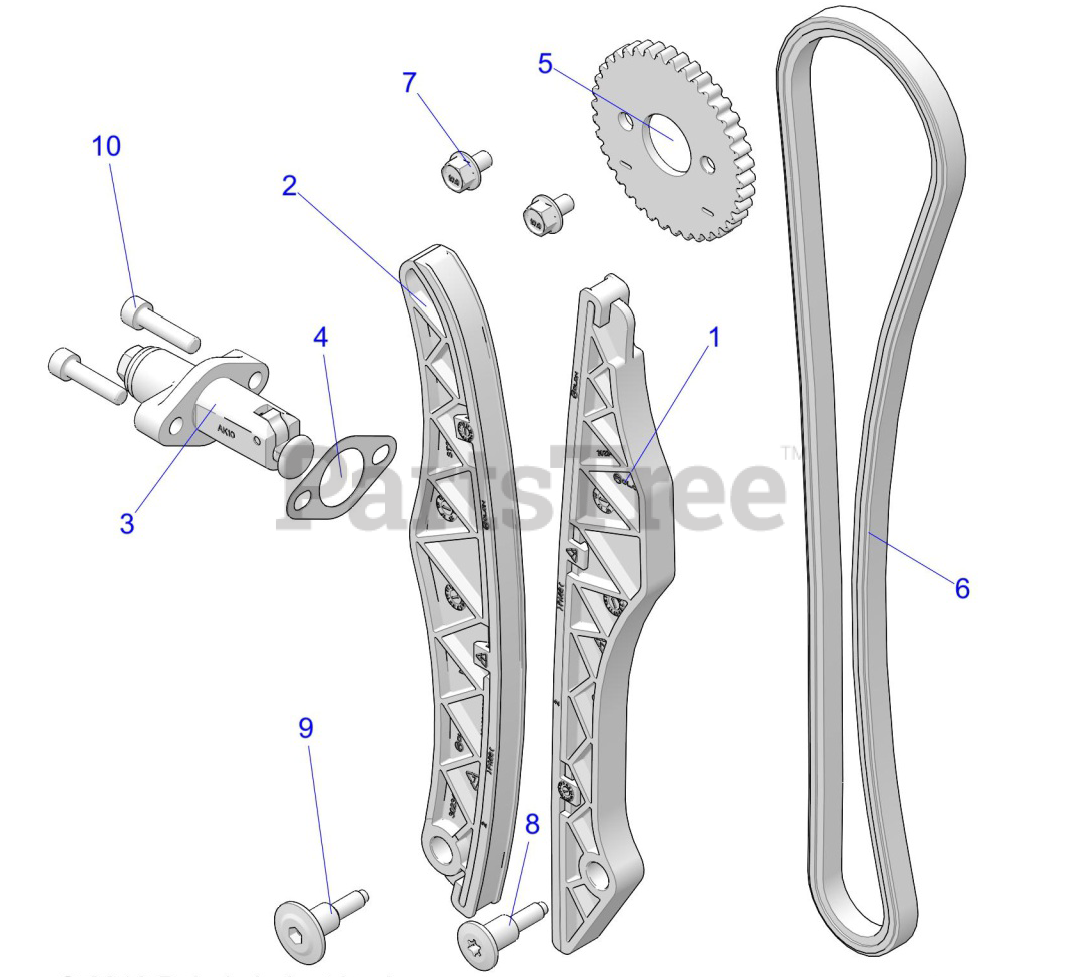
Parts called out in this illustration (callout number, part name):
1	GUIDE-CAM CHAIN,FIXED,SOHC
2	GUIDE-CAM CHAIN.TENSIONER,SOHC
3	TENSIONER-RATCHETING,MECH
4	GASKET, TENSIONER
5	SPROCKET-CAM,DRIVEN,SOHC
6	CHAIN-CAMSHAFT
7	SCR-HXFL,M6X1.0X10 10.9
8	BOLT-SHLDR,M6X12X15
10	SCR-SH-M6X1.0X25 10.9 ZPC D204
